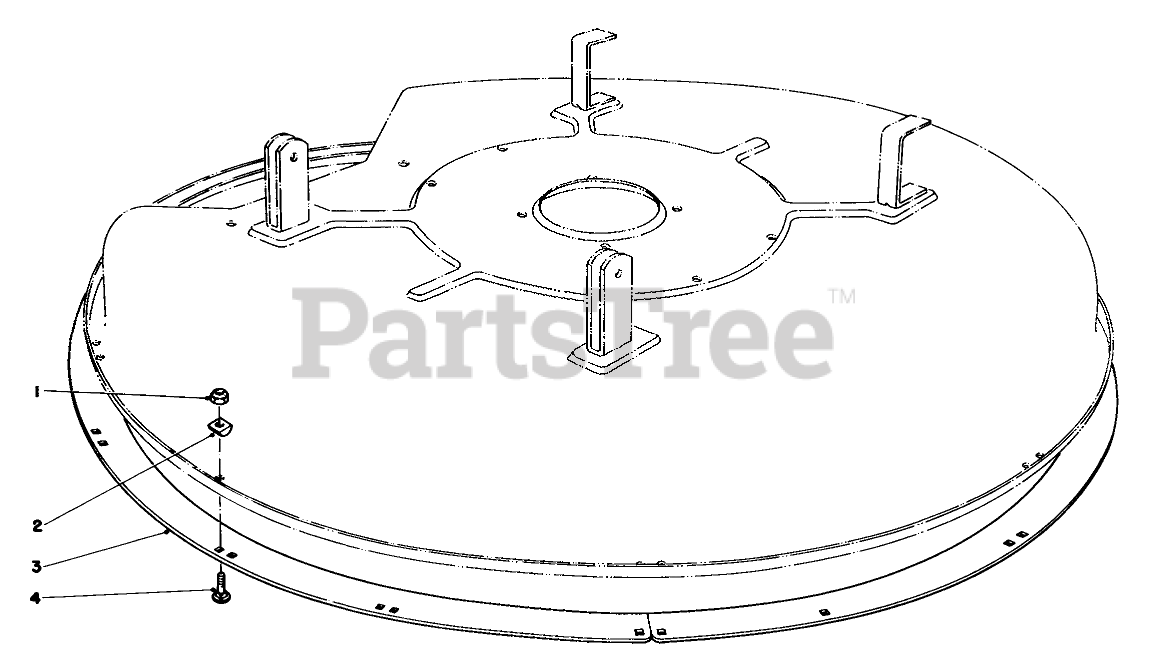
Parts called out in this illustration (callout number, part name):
1	NUT-LOCK, NI
2	Spacer-Deck Ring
3	DECK RING B
4	BOLT-CARR
